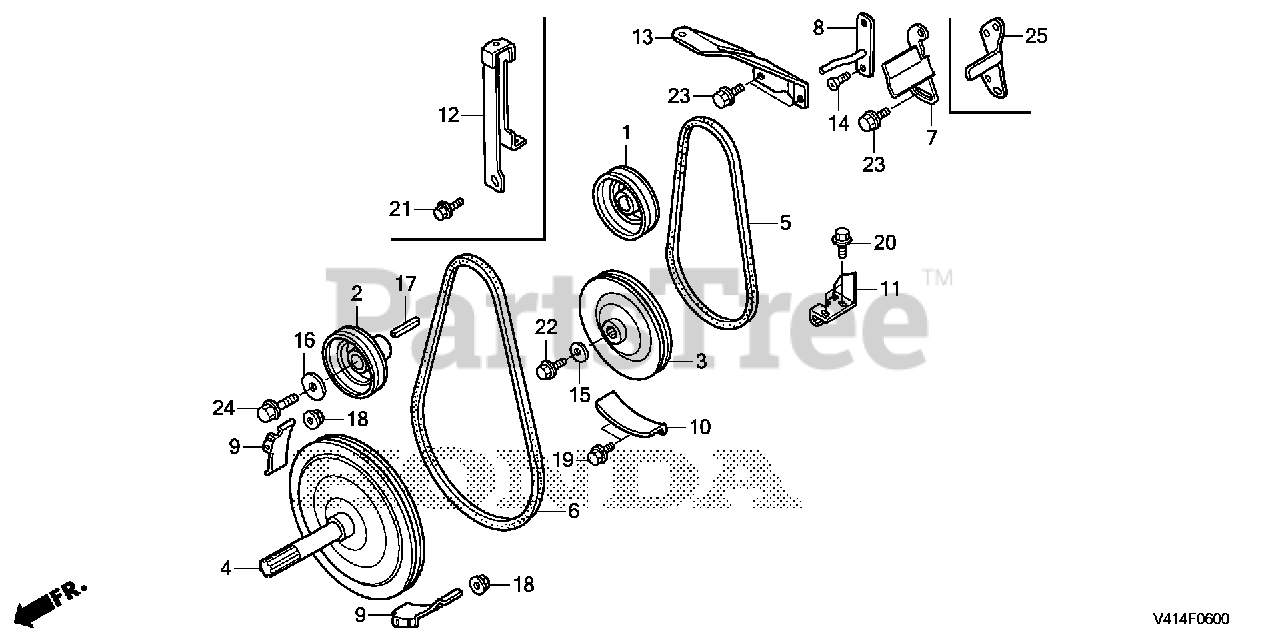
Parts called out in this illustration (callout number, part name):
1	PULLEY, WHEEL DRIVEN
2	PULLEY, AUGER DRIVE
3	PULLEY, WHEEL DRIVEN (133MM)
4	PULLEY, AUGER DRIVEN (198MM)
5	V-BELT (SA-29)
6	V-BELT (SB-35)
8	STOPPER, L. BELT (R. SIDE)
9	STOPPER, AUGER BELT
10	PROTECTOR, BELT (WHEEL)
11	GUIDE, BELT
12	STAY, HEADLIGHT
14	BOLT, DOOR LOCK STRIKER
15	WASHER, CAMSHAFT SIDE
16	WASHER, LOCK (8MM)
17	KEY (7X7X33)
18	NUT, FLANGE (6MM)
19	BOLT, FLANGE (6X12) Use up to Engine SN 1543277.
20	BOLT, FLANGE (6X14)
21	BOLT, FLANGE (6X16) Use from Engine SN 2056820.
22	BOLT, FLANGE (6X16)
23	BOLT, FLANGE (8X16) Use from Engine SN 1000016.
24	BOLT, FLANGE (8X28)
25	STOPPER, R. BELT (L. SIDE)
